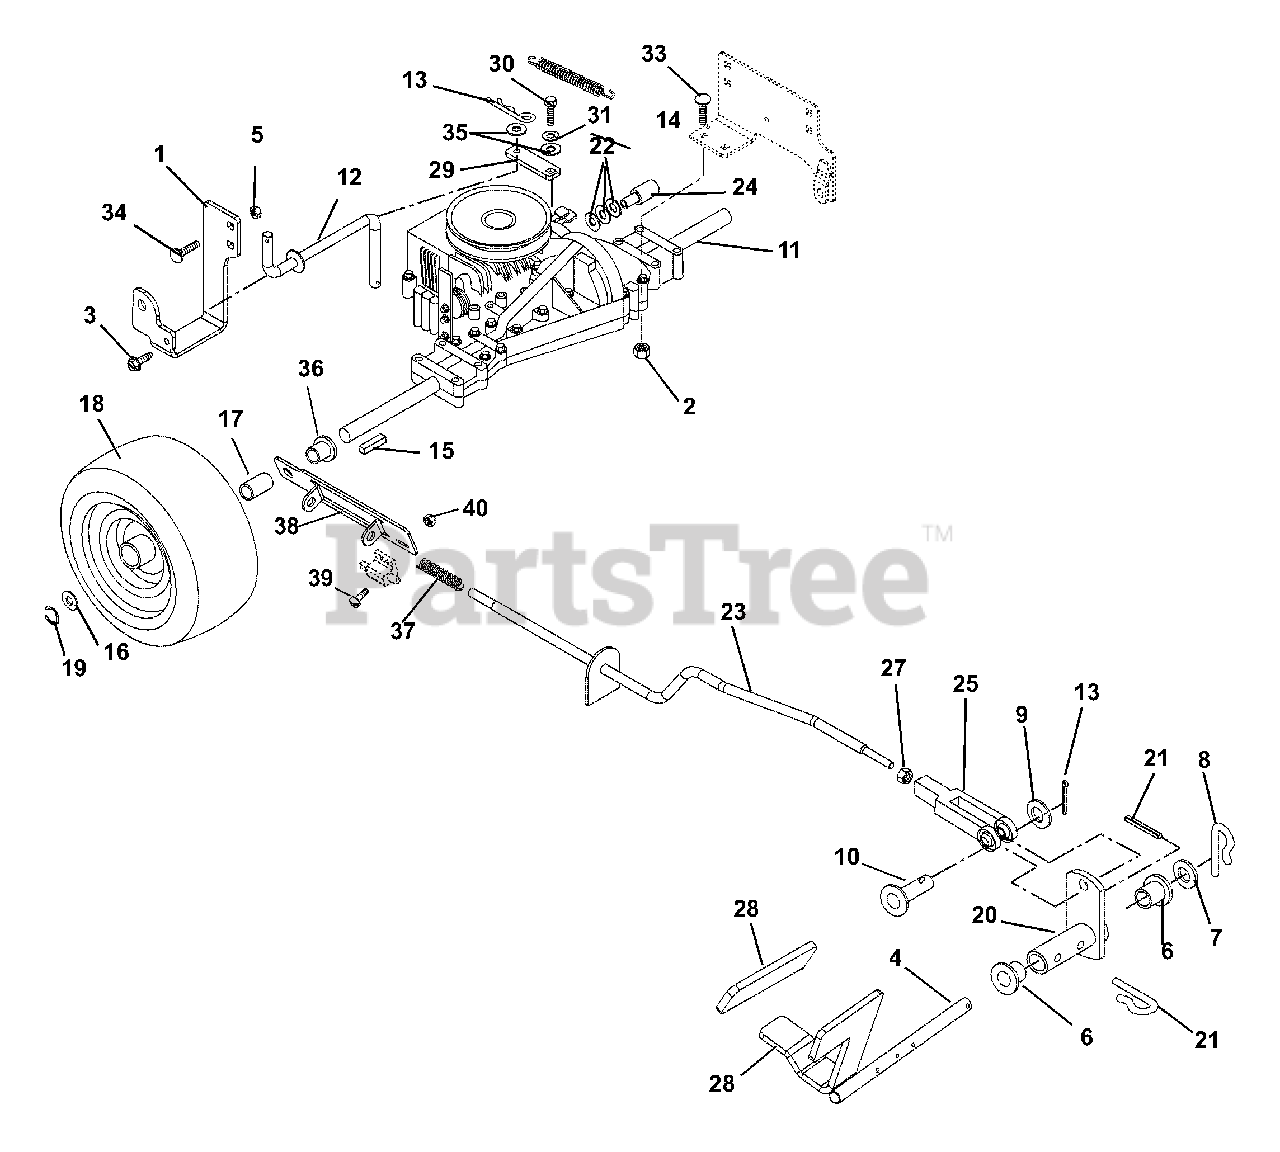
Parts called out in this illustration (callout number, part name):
1	Support, Transmission
2	Nut, Flange .50-13
3	Screw-Tapping .31-18 x .75 Hex Washer Head
4	Weldment, NMIR Shift Pedal
5	Nut, Locking Top Flange .38-16
6	Bushing, Flange .515 x .75 x .745 x 1.00
7	Washer, Flat Steel .505 x 1.00 x .062
8	Clip, Spring
9	Washer, Flat Steel .38 x .87 x .179
10	Pin, Clevis .31 x .822
11	Transmission Peerless Hydro
12	Rod, Transmission Disconnect
13	Pin, Hair
14	Spring, Tension .043 x .44 x 3.31
15	Key, Square .188 x 2.0 x .188
16	Washer, Flat Steel .755 x 1.25 x .125
17	Spacer, Wheel .75 x 1.00 x 1.25
18	Assembly, Tire and Wheel 16 x 6.5 x 8 (060, 062)
18	Tire 16 x 6.50-8 2 Pulley
19	Ring, Retaining External .75 x .05
20	Weldment, Shift Rod and Hub
21	Pin, Center .12 x 1.00 Extended Prong Square Cut
22	Washer, Flat, Steel .50 x 1.00 x .062
23	Rod, NMIR Shift
24	Trunnion
25	Yoke .31-24 x 2.250
26	Washer, Flat Steel .390 x .750 x .125
27	Nut-Locking-Nylon .375-24 With Insert
28	Grip, Pedal
29	Tab, Transmission Disconnect
30	Bolt-Hex .25-28 x .75 Grade 5
31	Washer, Locking .25 x .062 Regular
32	Washer, Flat Steel .328 x 1.00 x .094
33	Bolt, Round Head Square Neck .31-18 x 2.50 Grade 5
34	Bolt, Round Head Square Neck .38-16 x .75 Grade 5
35	Washer, Flat Steel .38 x .875 x .083
36	Bushing, Flange .406 x .88 x .270 x .140
37	Spring, Commpression .081 x .720 x 2.75
38	Bracket, NMIR Shift
39	Screw, Machine 10-24 x .75 HWH
40	Nut-Locking-Nylon 10-24 With Insert
